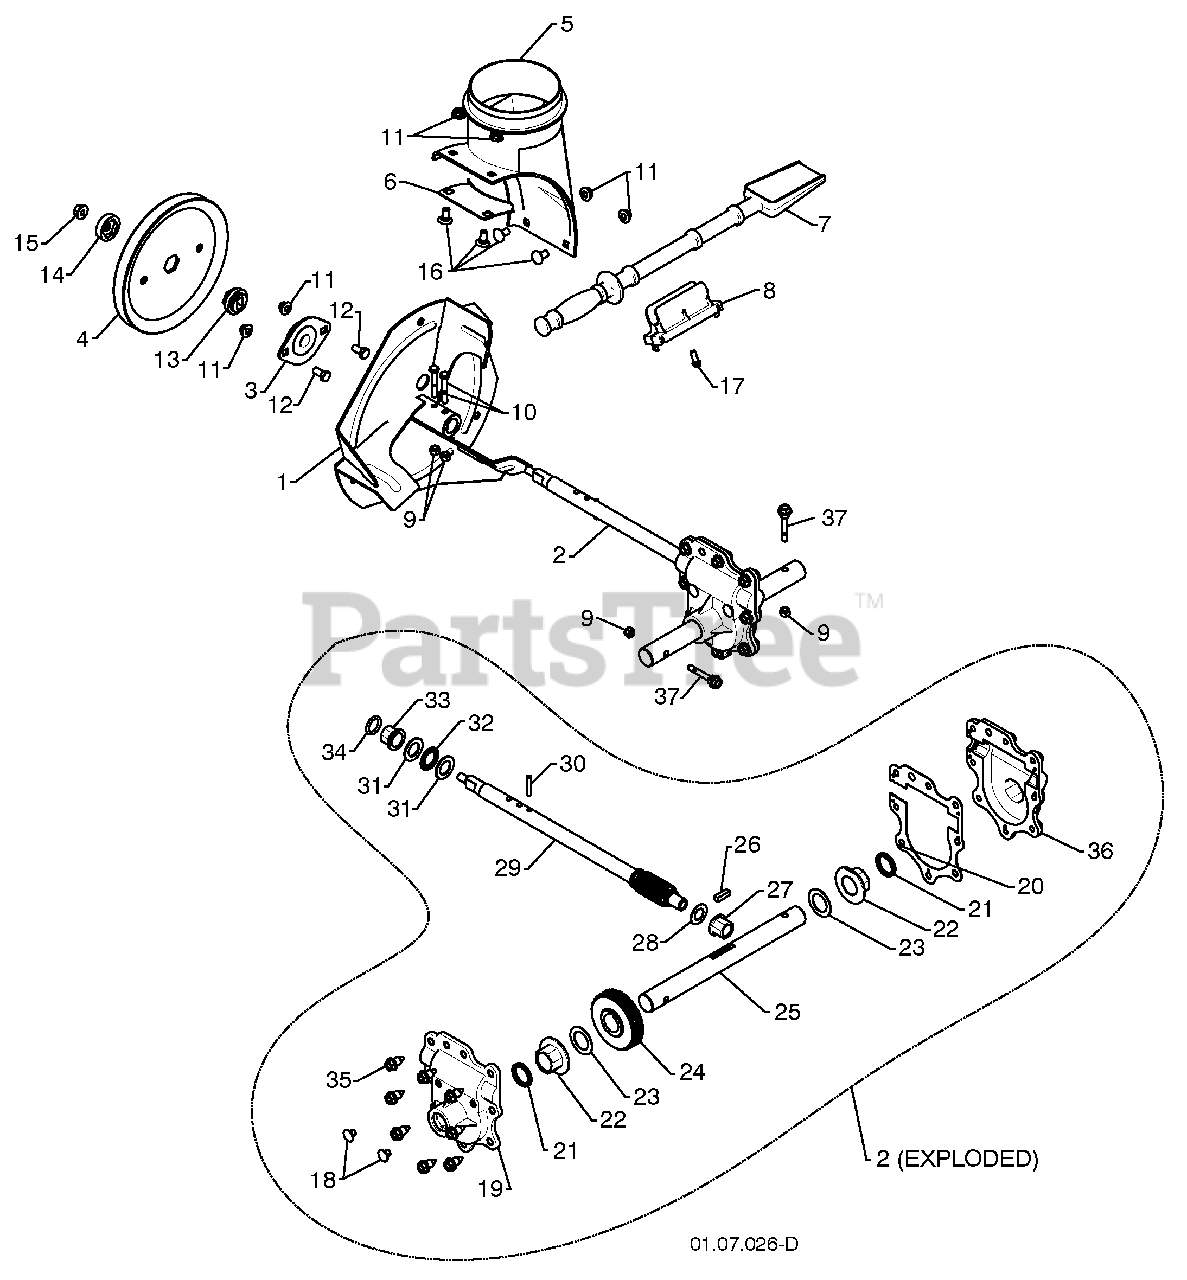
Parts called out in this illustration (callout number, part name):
1	IMPELLER
2	GEARBOX ASSEMBLY
3	BEARING
4	IMPELLER PULLEY
5	DISCHARGE BASE
6	CORNER BRACKET
7	CLEAN OUT TOOL
8	TOOL CLIP
9	NUT 1/4-20
10	SCREW 1/4-20 X .625
11	NUT 5/16-18
12	SCREW 5/16-18 X .625
13	IMPELLER HUB
14	IMPELLER SLEEVE
15	NUT 3/8-16
16	CARRIAGE BOLT
17	SCREW 13-16 X .625
19	GEARBOX COVER RH
20	GASKET
22	BEARING
23	THRUST WASHER 1.00
25	AUGER SHAFT
26	SQUARE KEY
28	THRUST WASHER
29	IMPELLER SHAFT
31	THRUST WASHER
32	THRUST BEARING
34	O-RING
35	SCREW 5/16-18 X .750
36	GEARBOX COVER LH
37	SHEAR BOLT
